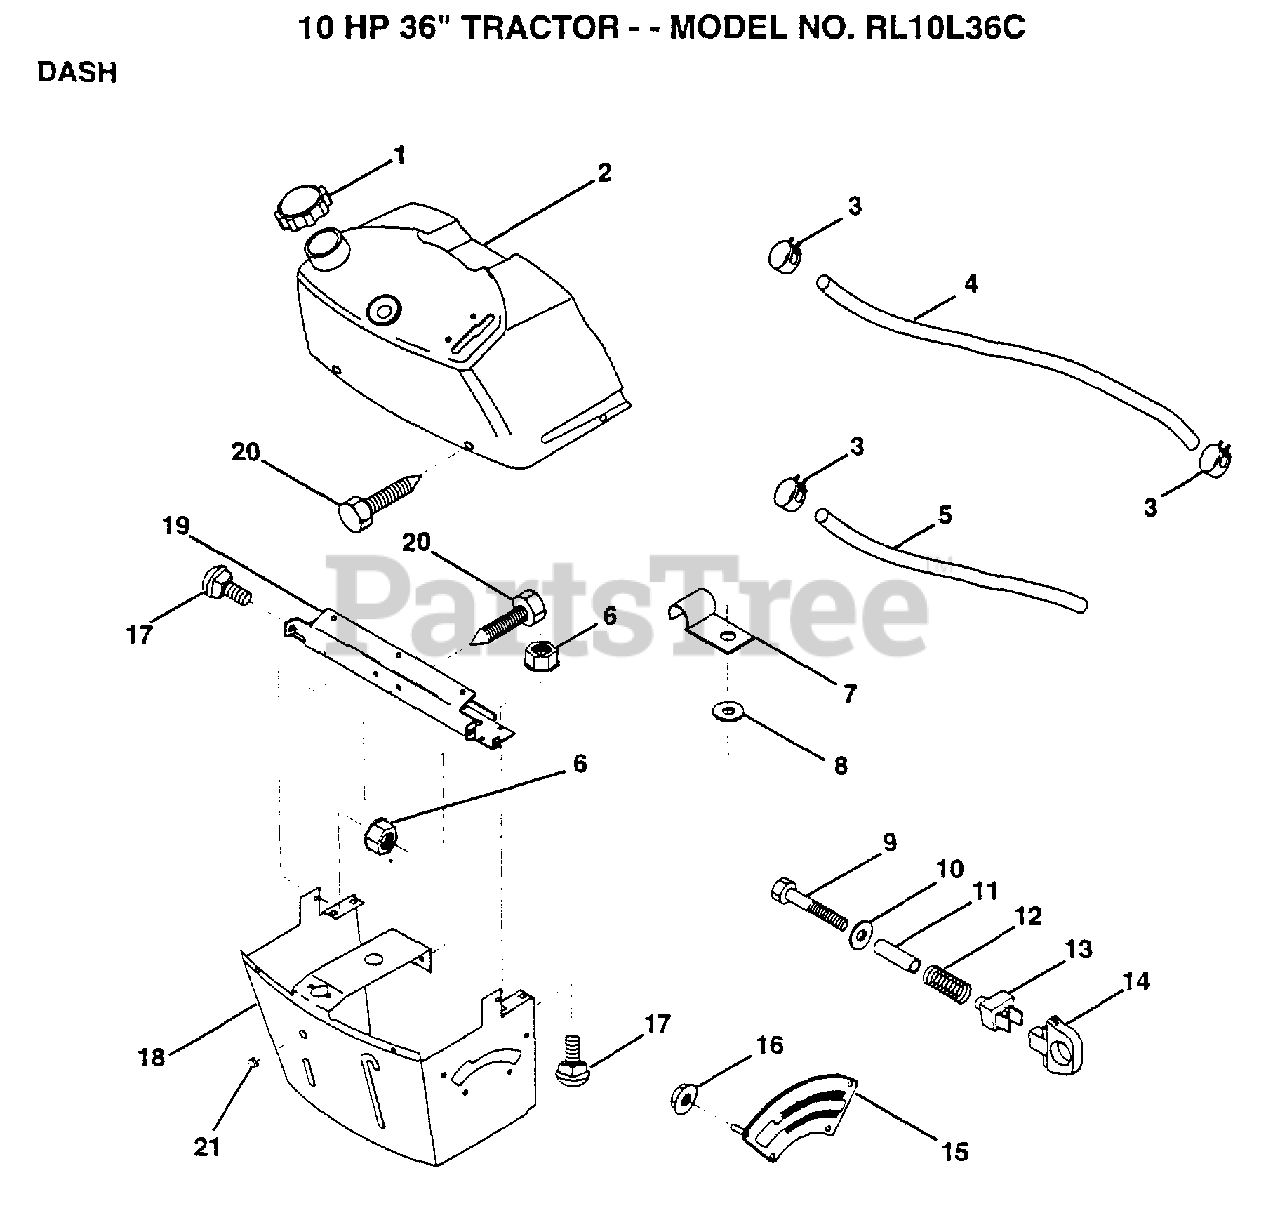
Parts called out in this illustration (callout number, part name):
1	CAP BLK FUEL LR
2	TANK.ASM.DASH.LR
3	HOSE CLAMP
5	FUEL LINE T
6	NUT
7	CLIP T
8	WASHER PM
9	BOLT
11	SPACER SPLIT
12	SPRING M
13	"KNOB,HGT RETAINER"
14	KNOB
15	ADJUSTER QUAD
16	NUT
17	BOLT
18	SUPT ASSY DASH
19	CROSS BRACE
20	SCREW.1/4-20X1/2
21	PLUG DOME
